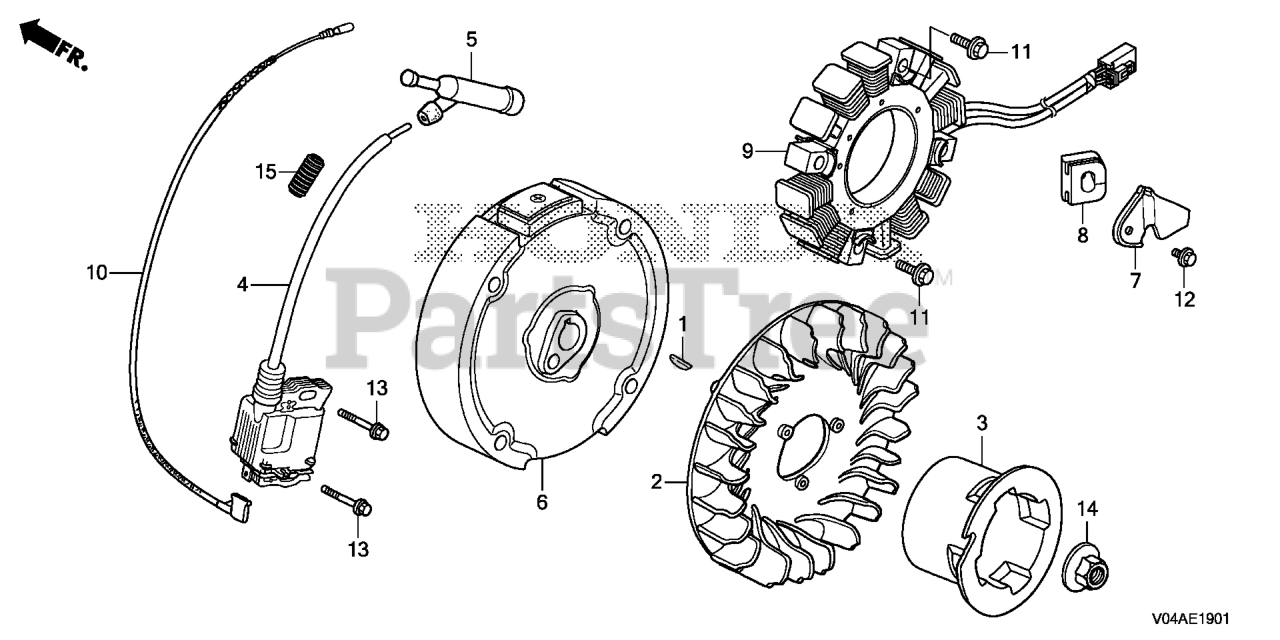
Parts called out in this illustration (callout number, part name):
1	KEY, SPECIAL WOODRUFF (25X18)
2	FAN, COOLING
3	PULLEY, STARTER
4	COIL ASSY., IGNITION (TEC)
5	CAP ASSY., NOISE SUPPRESSOR (TEC)
7	CLAMP, WIRE
8	GROMMET, WIRE
9	COIL ASSY., LAMP
10	WIRE, STOP SWITCH (370MM)
11	BOLT, FLANGE (6X28) (CT200) Use up to Engine SN 1530314.
12	BOLT, FLANGE (5X10)
13	BOLT, FLANGE (6X25) Use up to Engine SN 2056819.
14	NUT, SPECIAL (14MM)
